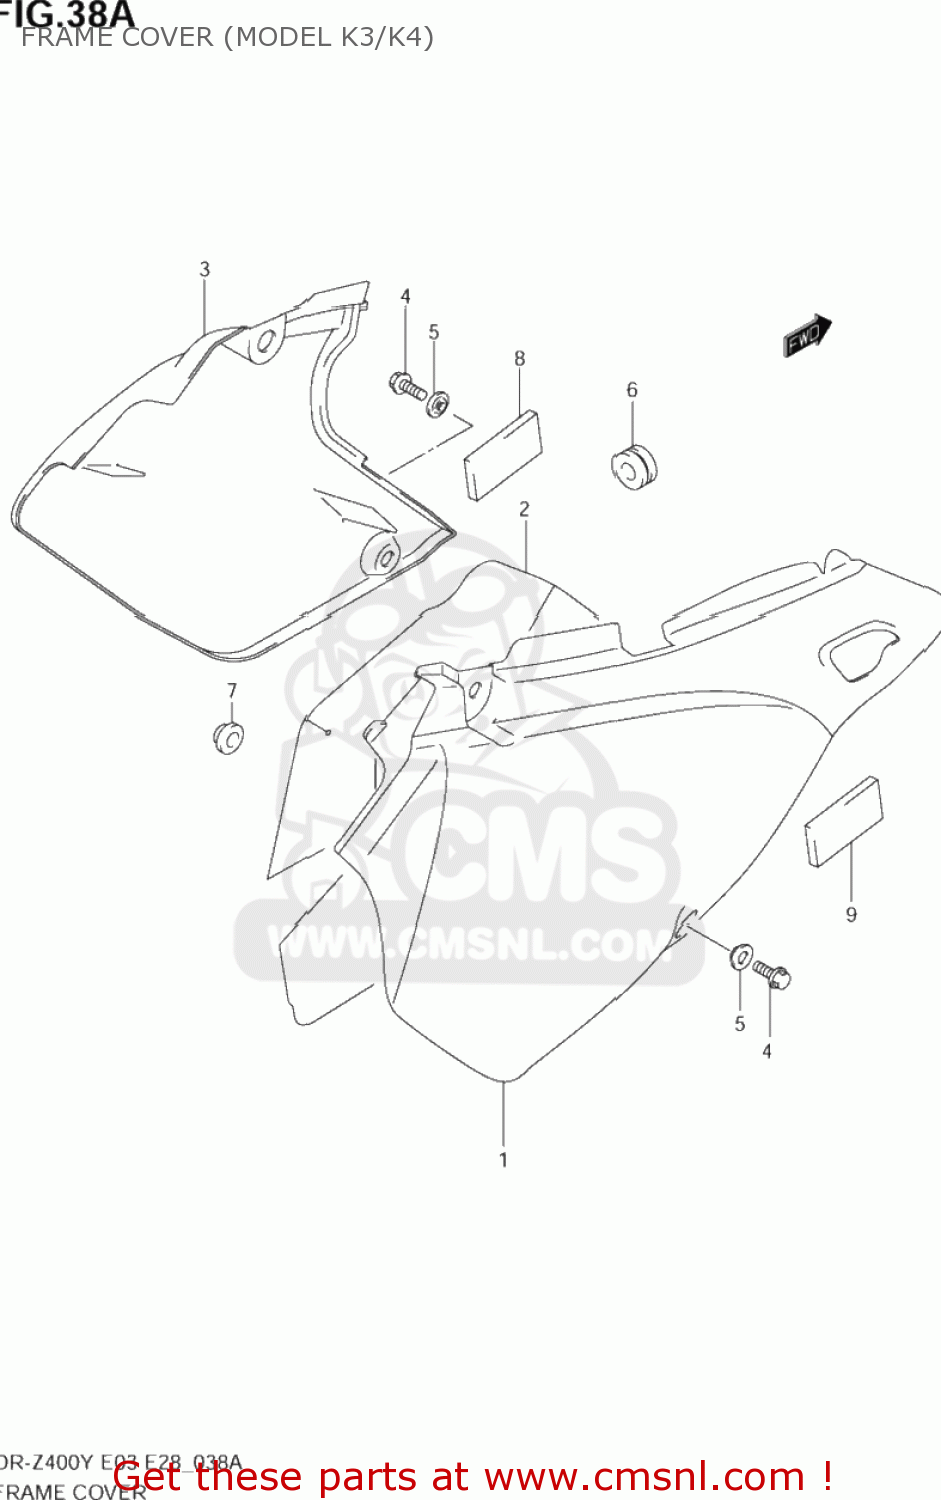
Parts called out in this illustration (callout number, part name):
1	COVER,FRAME,RIGHT
2	SHIELD,FRAME COVER,R
3	COVER,FRAME,LEFT
4	BOLT
5	WASHER
6	CUSHION
7	CUSHION
8	CUSHION,FRAME COVER,L
9	CUSHION
